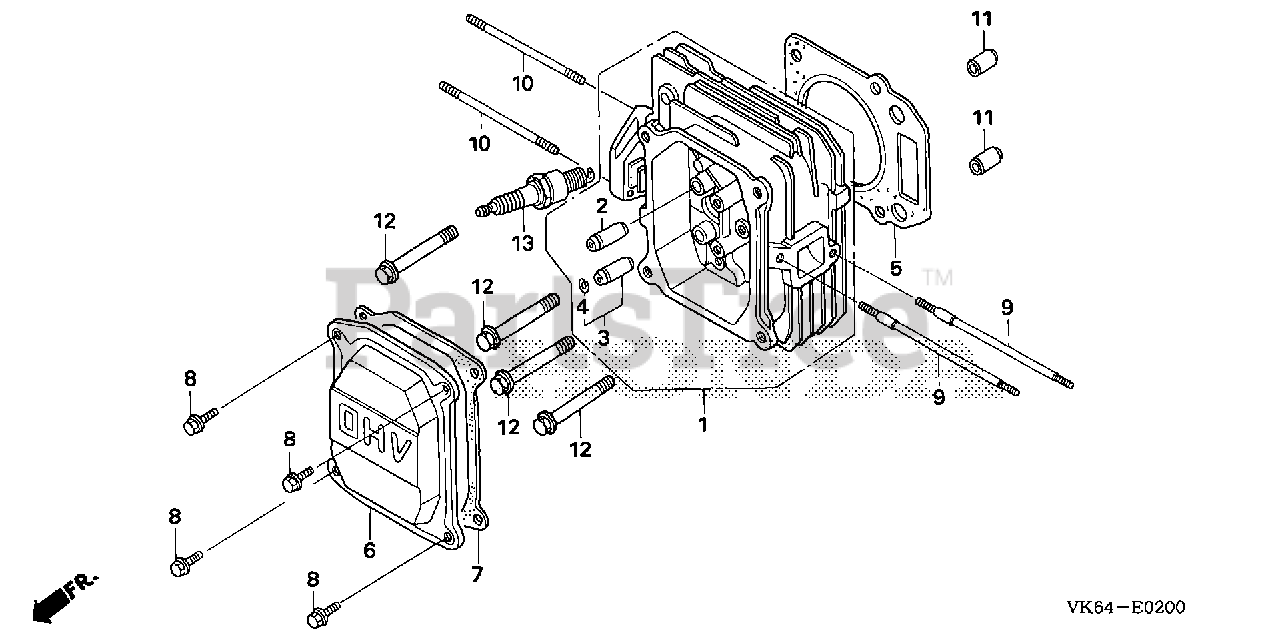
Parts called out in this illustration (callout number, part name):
1	CYLINDER HEAD
2	GUIDE, VALVE (OVER SIZE)
3	GUIDE, EX. VALVE (OVER SIZE)
4	CLIP, VALVE GUIDE
5	GASKET, CYLINDER HEAD
5	GASKET, CYLINDER HEAD (GUANGZHOU LEAKLESS)
5	GASKET, CYLINDER HEAD (NINGBO SIL GASKET)
6	COVER, HEAD
7	GASKET, HEAD COVER (NINGBO SIL GASKET)
7	GASKET, HEAD COVER
8	BOLT, FLANGE (6X14) (CT200)
9	BOLT, STUD (6X109)
9	BOLT, STUD (6X97)
10	BOLT, STUD (6X85)
11	PIN, DOWEL (10X16)
12	BOLT, FLANGE (8X50)
13	SPARK PLUG (BPR4ES) (NGK)
13	SPARK PLUG (W14EPR-U) (DENSO)
13	SPARK PLUG (BPR5ES) (NGK)
13	SPARK PLUG (W16EPR-U) (DENSO)
13	SPARK PLUG (BPR6ES) (NGK)
13	SPARK PLUG (W20EPR-U) (DENSO)
